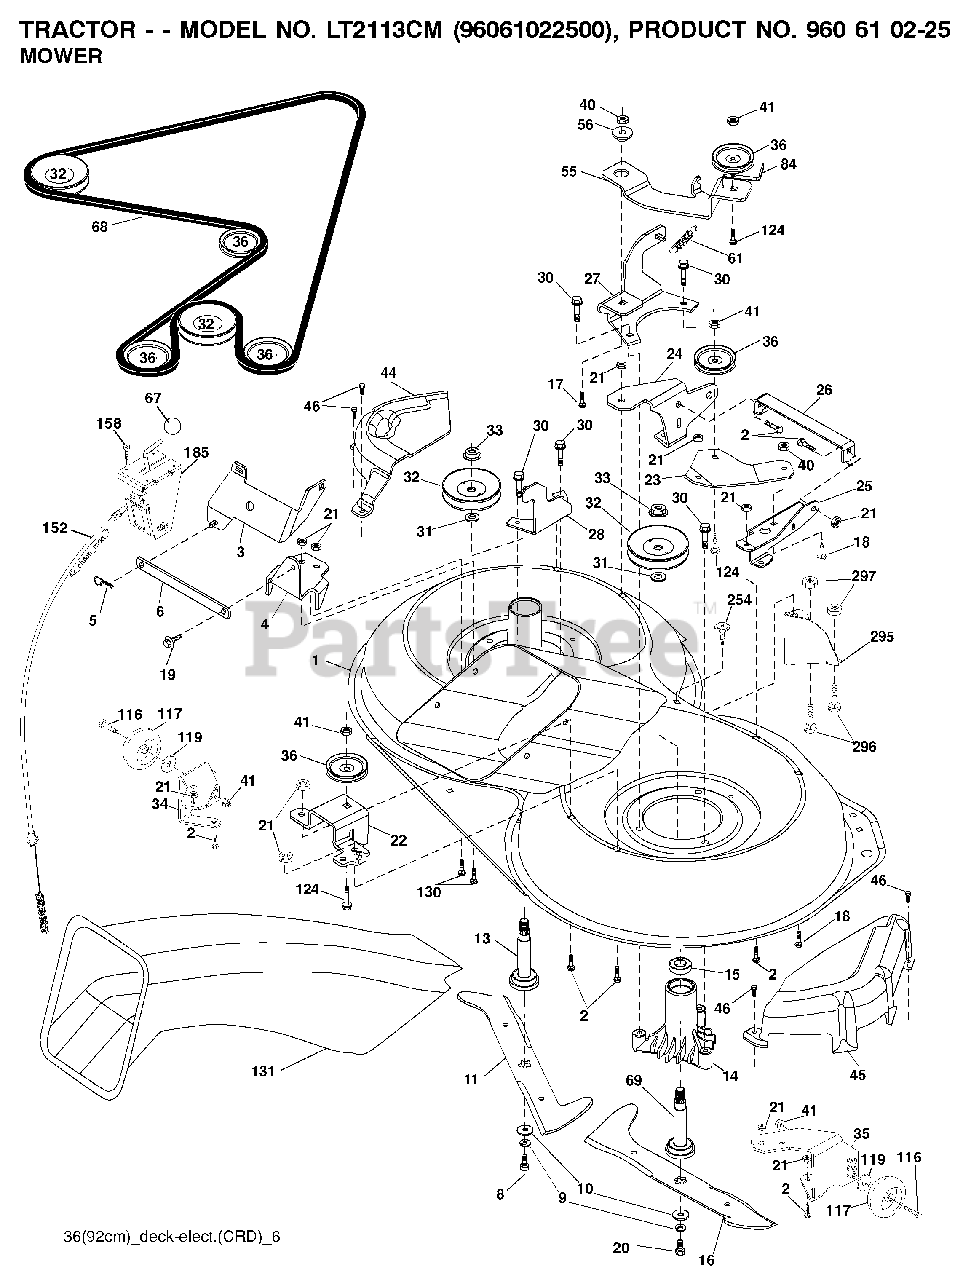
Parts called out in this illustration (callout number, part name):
2	BOLT
3	BRACKET
5	RETAINER-SPRNG RB
6	BAR SWAY
9	LOCKWASHER
10	WASHER.BLADE
13	SHAFT ASM VENT
14	HSG MANDREL
17	BOLT.3/8-14X1.25
19	BOLT SHD 5/16-18
21	LOCKNUT
24	BRACKET
25	BRACKET
28	BRACKET
30	SCREW, WASHER HEAD
31	WASHER.SPACER.MANDREL
32	PULLEY MANDREL
33	NUT.FLANGE.LOCK.TOP
36	PULLEY.IDLER.4.25
40	LOCKNUT
41	NUT LOCK FLG 3/8-16 UNC
45	MANDREL COVER
46	SCREW.1/4-20X5/8
56	SPACER.RETAINER.MOWER
67	KNOB T (3/8 HOLE)
69	SHAFT.ASM.W/LWR.BRG.RH.THREAD
84	KEEPER, BELT IDLER
116	BOLT.SHOULDER.3/8-16X3-5/8
117	WHEEL. GUAGE RALLY
124	BOLT.3/8-16X1.50
131	CHUTE BAGGER
158	SCREW
185	HEAD ASM. CABLE CLUTCH
254	SCREW 3/8-16X1
296	BOLT
297	NUT CENTERLOCK
